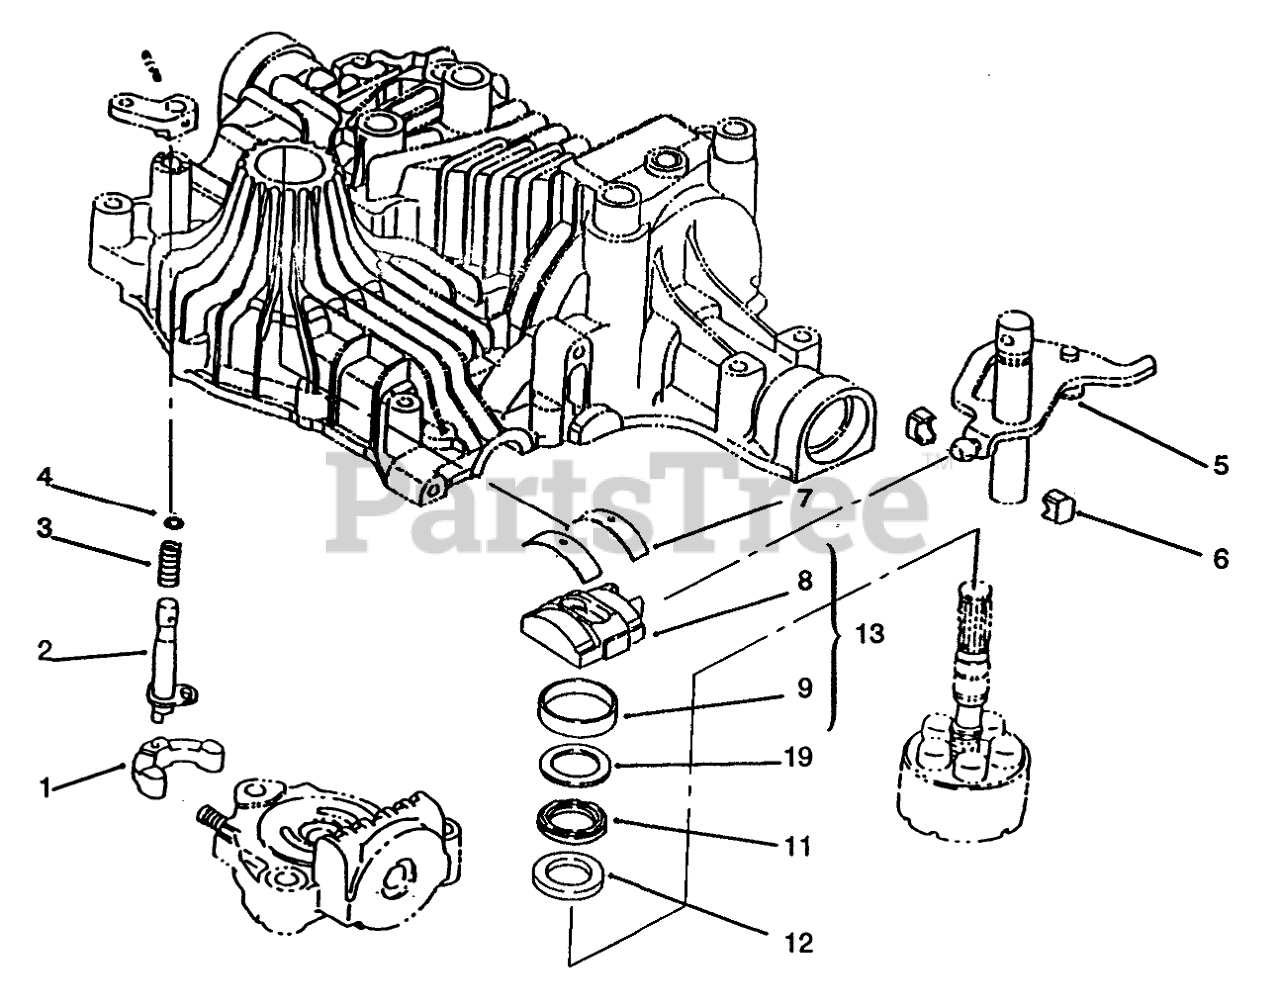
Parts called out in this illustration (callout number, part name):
1	Arm (Only On: 72083, 72043, 72103, 72063)
2	Shaft-Bypass (Only On: 72083, 72043, 72103, 72063)
3	Spring (Only On: 72083, 72043, 72103, 72063)
4	Packing (Only On: 72083, 72043, 72103, 72063)
5	Block Set INC 6 (Only On: 72083, 72043, 72103, 72063)
7	Thrust Metal (Only On: 72083, 72043, 72103, 72063)
10	Plate-Thrust (Only On: 72083, 72043, 72103, 72063)
11	Bearing (Only On: 72083, 72043, 72103, 72063)
12	Plate-Thrust (Only On: 72083, 72043, 72103, 72063)
13	Swash Plate INC 8-9 (Only On: 72083, 72043, 72103, 72063)
